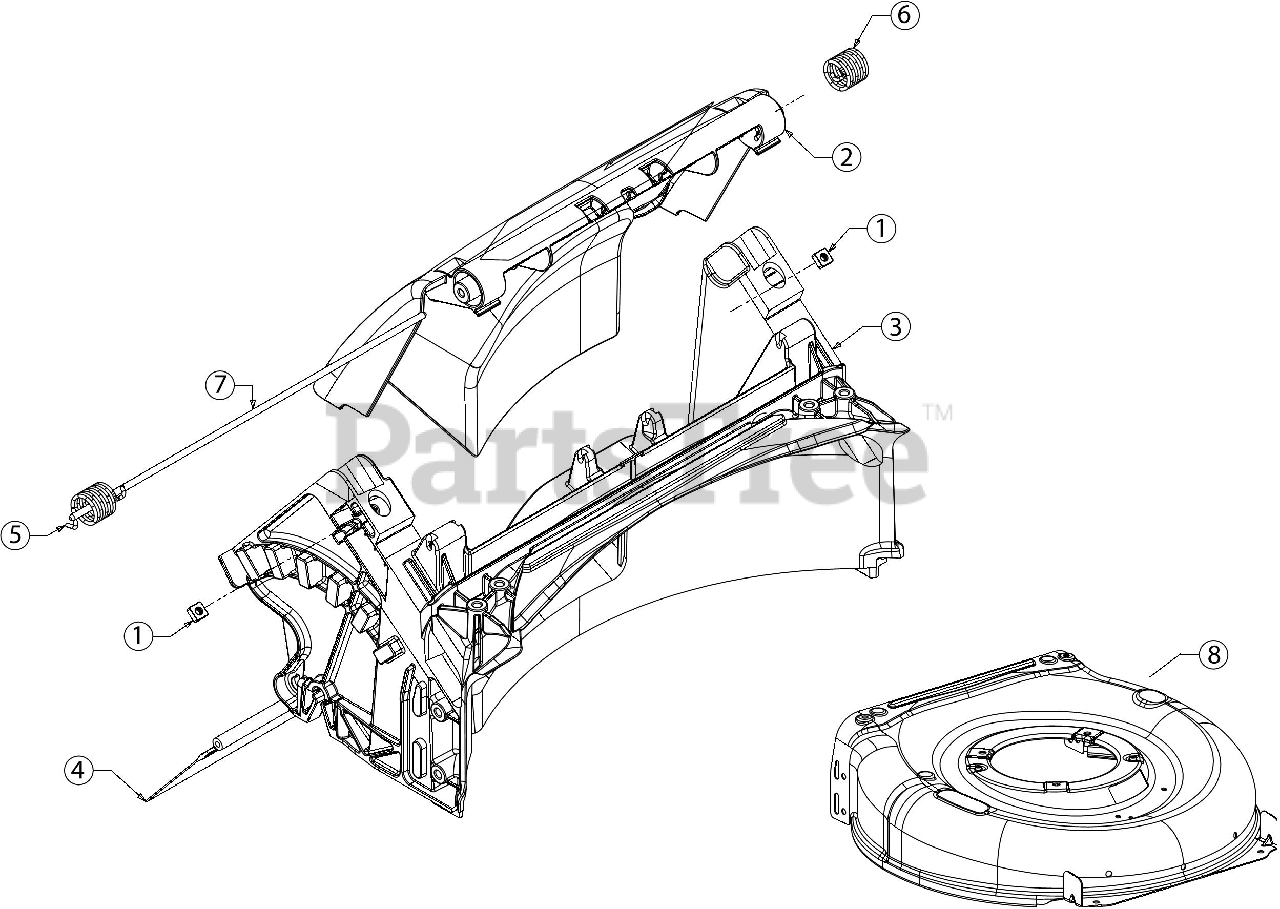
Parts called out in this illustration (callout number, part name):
1	SQUARE NUT 1/4-20
3	DOOR ASSEMBLY
4	TRAILSHIELD
5	TORSION SPRING (RH)
6	TORSION SPRING (LH)
7	REAR DOOR PIVOT ROD
8	21" DECK (2N1) (MTD RED)
